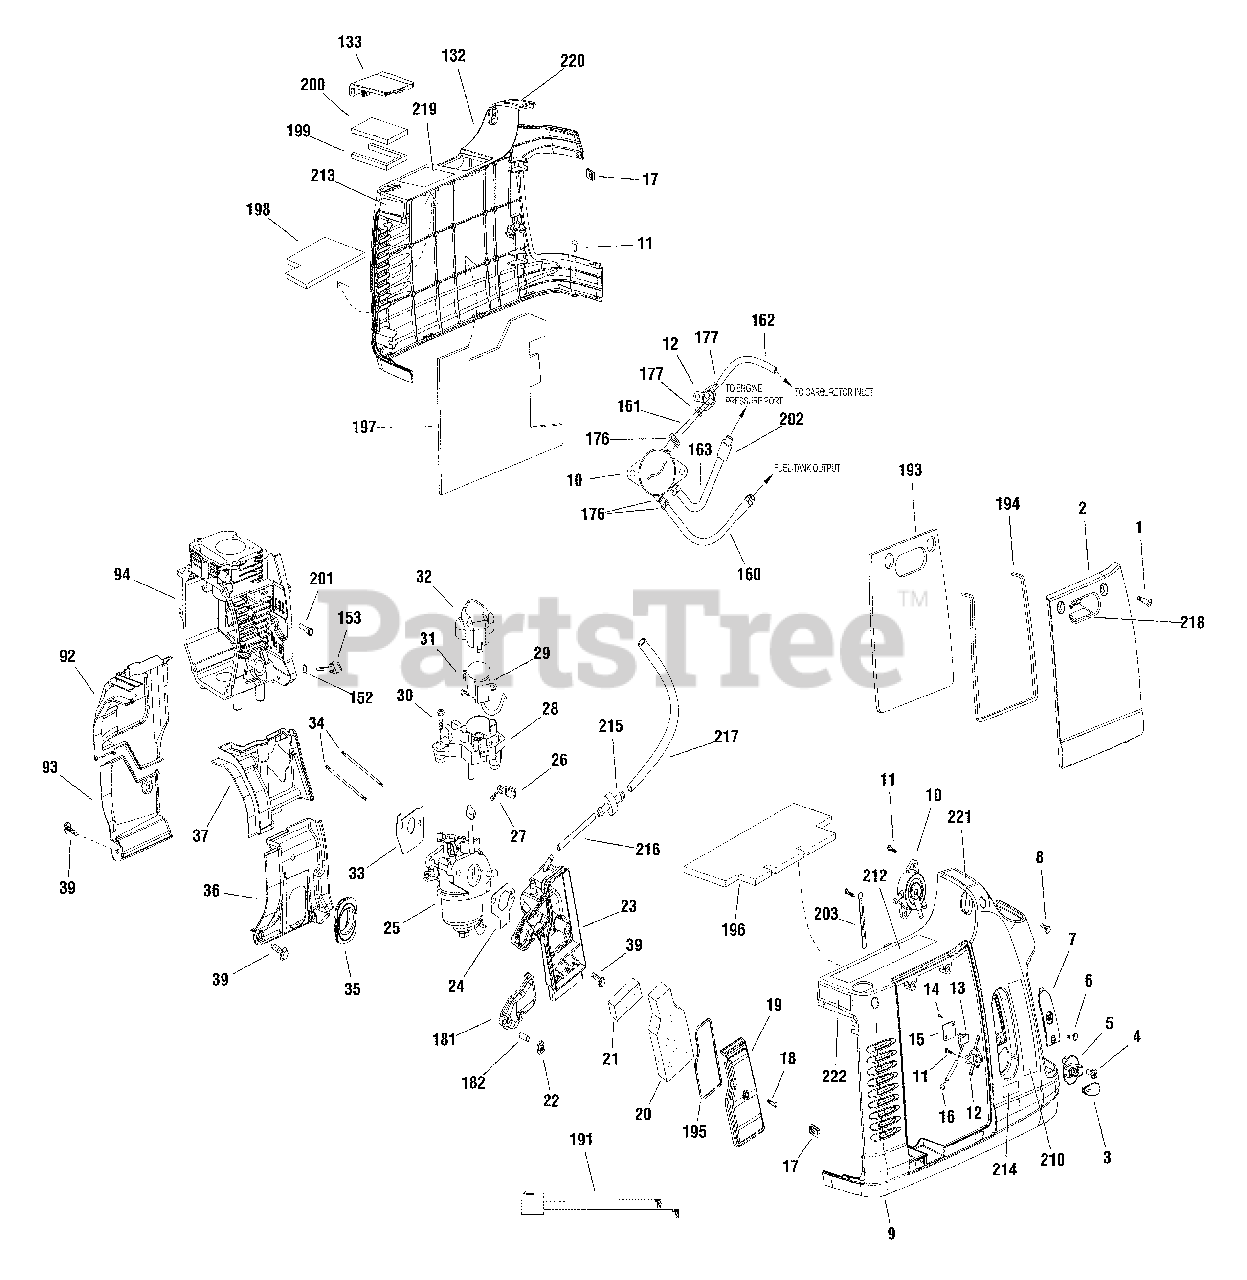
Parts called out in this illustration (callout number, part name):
4	BOLT
10	PUMP, Fuel
11	SCREW
14	BOLT
15	COVER, Switch
16	CONNECTION
17	NUT
19	COVER, Air Cleaner
20	FILTER, A/C Foam
21	FILTER, A/C Foam
22	NUT
23	BASE, Air Cleaner
24	GASKET, Air Cleaner
27	SPRING
30	BOLT
31	BOLT
35	SEAL, Rubber
36	DEFLECTOR
37	DEFLECTOR
92	DEFLECTOR
93	DEFLECTOR
94	CRANKCASE
133	COVER, Spark Plug
176	CLAMP
177	CLAMP
181	COVER, Air Cleaner
182	SLEEVE
193	FOAM
194	SEAL
195	SEAL
196	FOAM
197	FOAM
198	FOAM
199	SEAL
200	FOAM
201	CYLINDER, Breather Tube
202	TUBE
203	BRACKET
